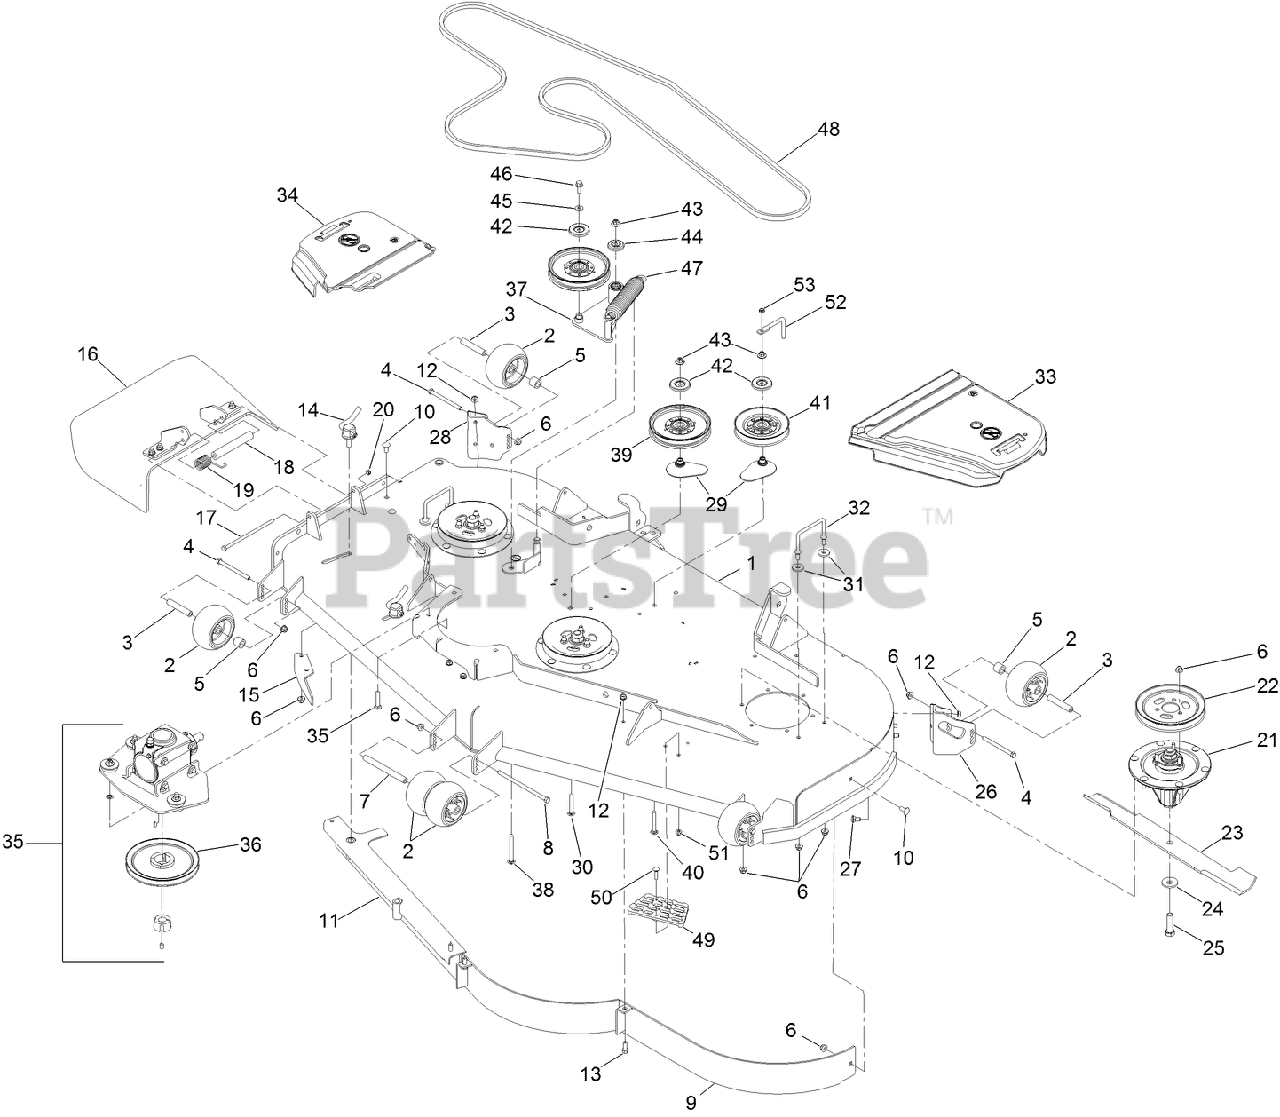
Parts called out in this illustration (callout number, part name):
1	DECK DECAL ASM
2	ROLLER-SCALP, ANTI
3	TUBE-SPANNER
4	SCREW-HH
5	TUBE-SPACER
6	NUT-HF, NI
7	SPACER-WHEEL
8	SCREW-HH
10	SCREW-CARR
11	BAFFLE ASM
12	NUT-HHF, WHIZ
14	LEVER ASM
15	BAFFLE-DISCHARGE
16	RUBBER DEFLECTOR ASM
17	SCREW-HH
18	SPACER
19	SPRING-TORSION
20	NUT-LOCK, NI
21	SPINDLE ASM
22	PULLEY
23	BLADE-HI FLOW, 24.5 INCH
24	WASHER-BLADE BOLT, HEAVY
25	SCREW-BLADE
26	MOUNT-WHEEL, LH
27	SCREW-CARR
28	MOUNT-WHEEL, RH
29	SPACER-PULLEY
30	SCREW-CARR
31	WASHER
32	WIREFORM-COVER
33	COVER-BELT, LH
34	SHIELD-BELT
35	GEARBOX ASM
36	PULLEY
37	IDLER ARM ASM
38	BOLT-SHOULDER, CARRIAGE
39	IDLER-PULLEY
40	SCREW-CARR
41	IDLER V
42	SHIELD-DUST
43	NUT-FLANGE, NI
44	GUARD-TOP
45	SPACER
46	SCREW-HHF
47	SPRING-EXTENSION
48	BELT-V
49	STEP-DECK
50	SCREW-CARR
51	NUT-HF, NI
52	GUIDE-BELT
